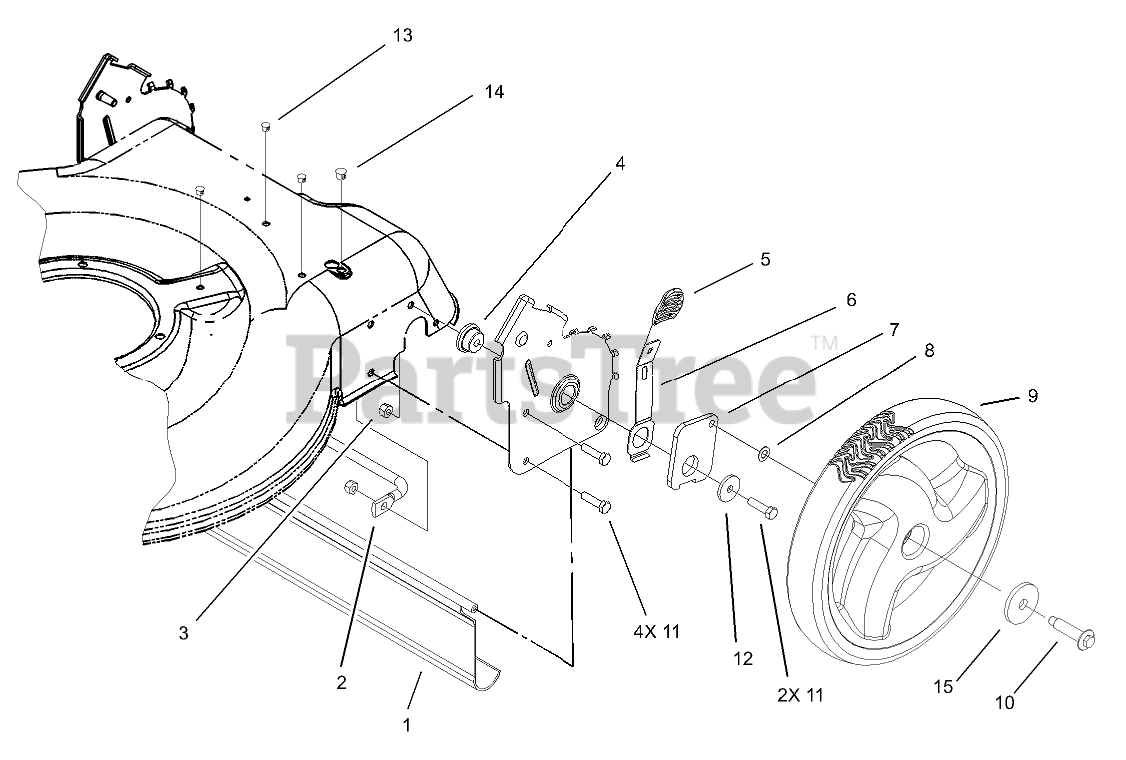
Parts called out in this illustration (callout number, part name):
1	Shield-Trailing
2	BRACE-PLATE, HOC
3	NUT-LOCK, NI
4	Bushing-Mount, HOC
5	Knob-Lever, HOC
6	Arm-Spring
7	Arm-Pivot, Rear
8	WASHER
9	Wheel ASM
10	BOLT-SHOULDER
11	SCREW-HH
12	Washer-Flat
13	Plug-Dome
14	Plug-Dome
15	WASHER-PLAIN
